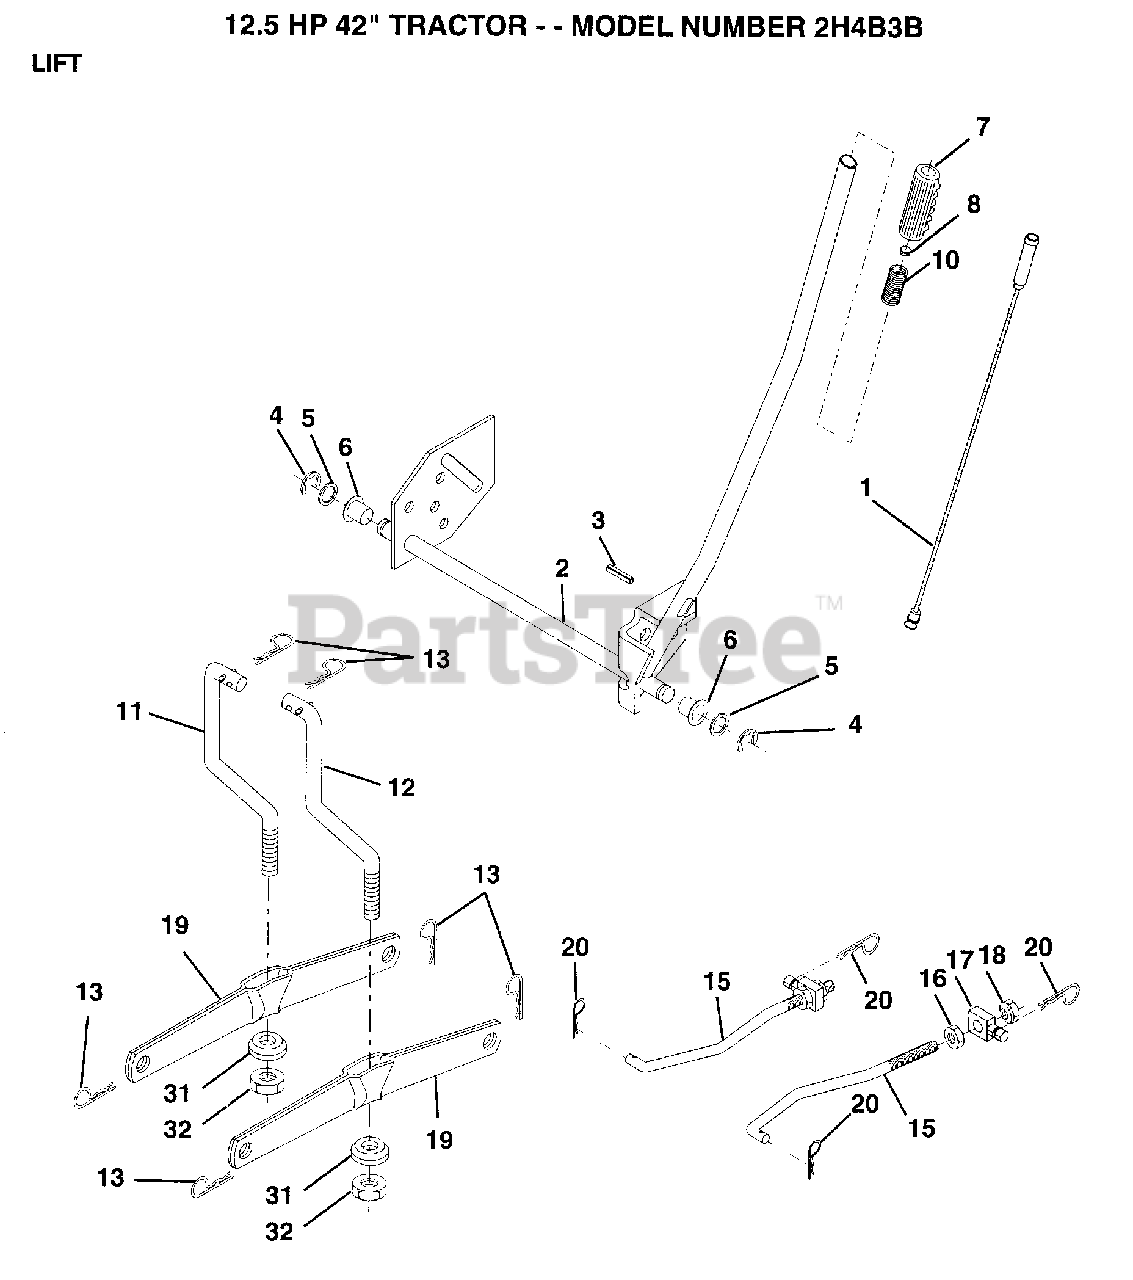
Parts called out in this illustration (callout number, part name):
1	WIRE ASM
3	PIN-GROOVE LT
5	WASHER
6	NYLON BEARING
7	GRIP
15	LINK.FRONT
16	NUT
17	TRUNION
18	NUT.LK.W/WSH.1/2.
19	ARM SUSP REAR
20	RETAINER.SPRING
31	BEARING PVT LH
32	NUT.HX.INS.NYLON
33	GRIPCO NUT
